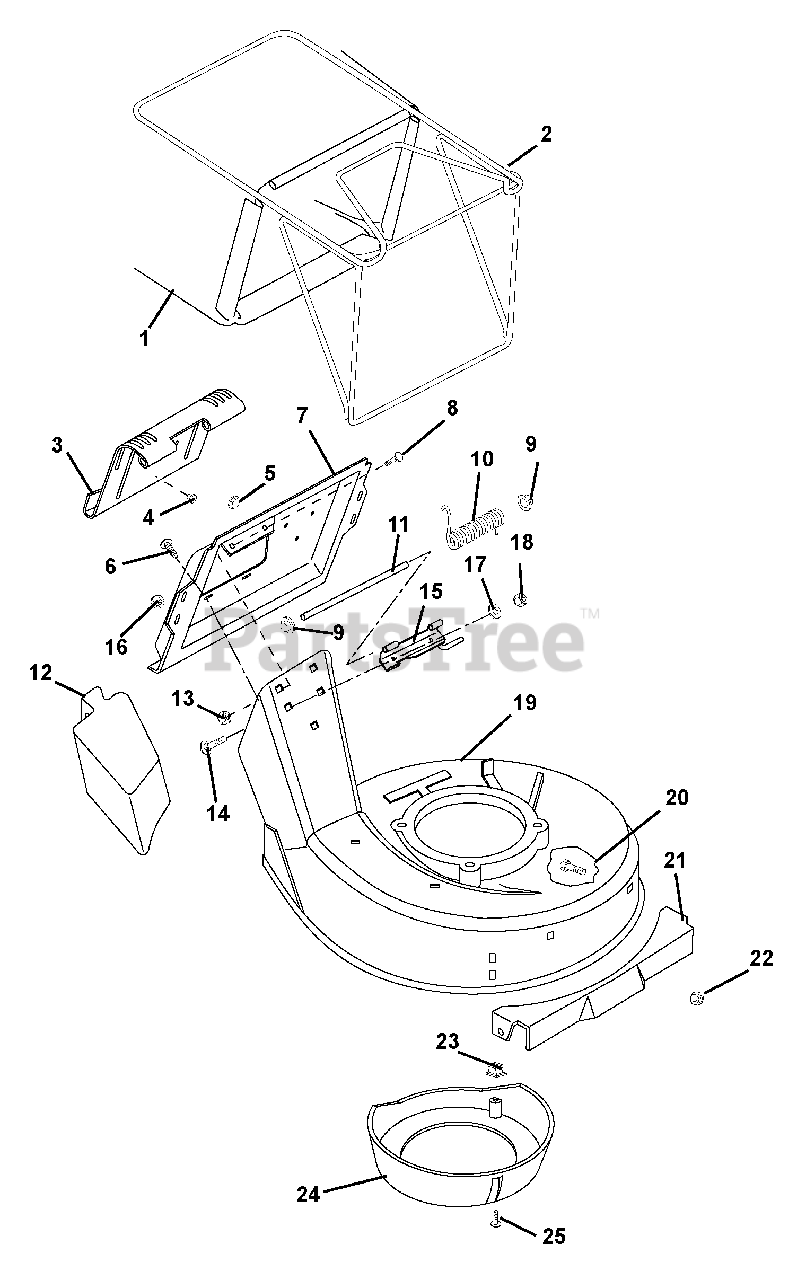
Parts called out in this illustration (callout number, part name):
1	BAG, CONSUMER BLACK 15 OZ/YD2
2	FRAME, WBLM BAGGER
3	CATCHER PLATE DOOR
4	BUTTON BUMPER
6	SCR-TAP 10-24X.375 TORX PHD YZ
7	PLATE, CATCHER
8	BLT-RHDSSQNK .25-20X.38 G2YZ
9	PUSH NUT, .25
10	SG-TORS .120X.68X3.09
11	DOOR PIN
12	MULCH MASTER MULCHER ACCESSORY
13	NUT-SPNLK-FLG .25-20 YWZC
14	BLT-RDHDSQNK .25-20X.75 G5YZ
15	HINGE PLATE WELDMENT
16	NUT-SPNLK-FLG .25-20 YWZC
17	WSHR-LK .250X.077 HVY YWZC
18	NUT-HEX .25-20 YWZC
19	MOWER PAN W/DECALS SP/COM
20	BLT-RDHDSQNK .31-18X.50 G5YZ
21	PANEL-FRONT
22	NUT-SPNLK-FLG .312-18 YWZC
23	PLASTIC GROMMET
24	CENTER BAFFLE
25	SCR-TAP 10-16X.62 SLPH AB YWZC
